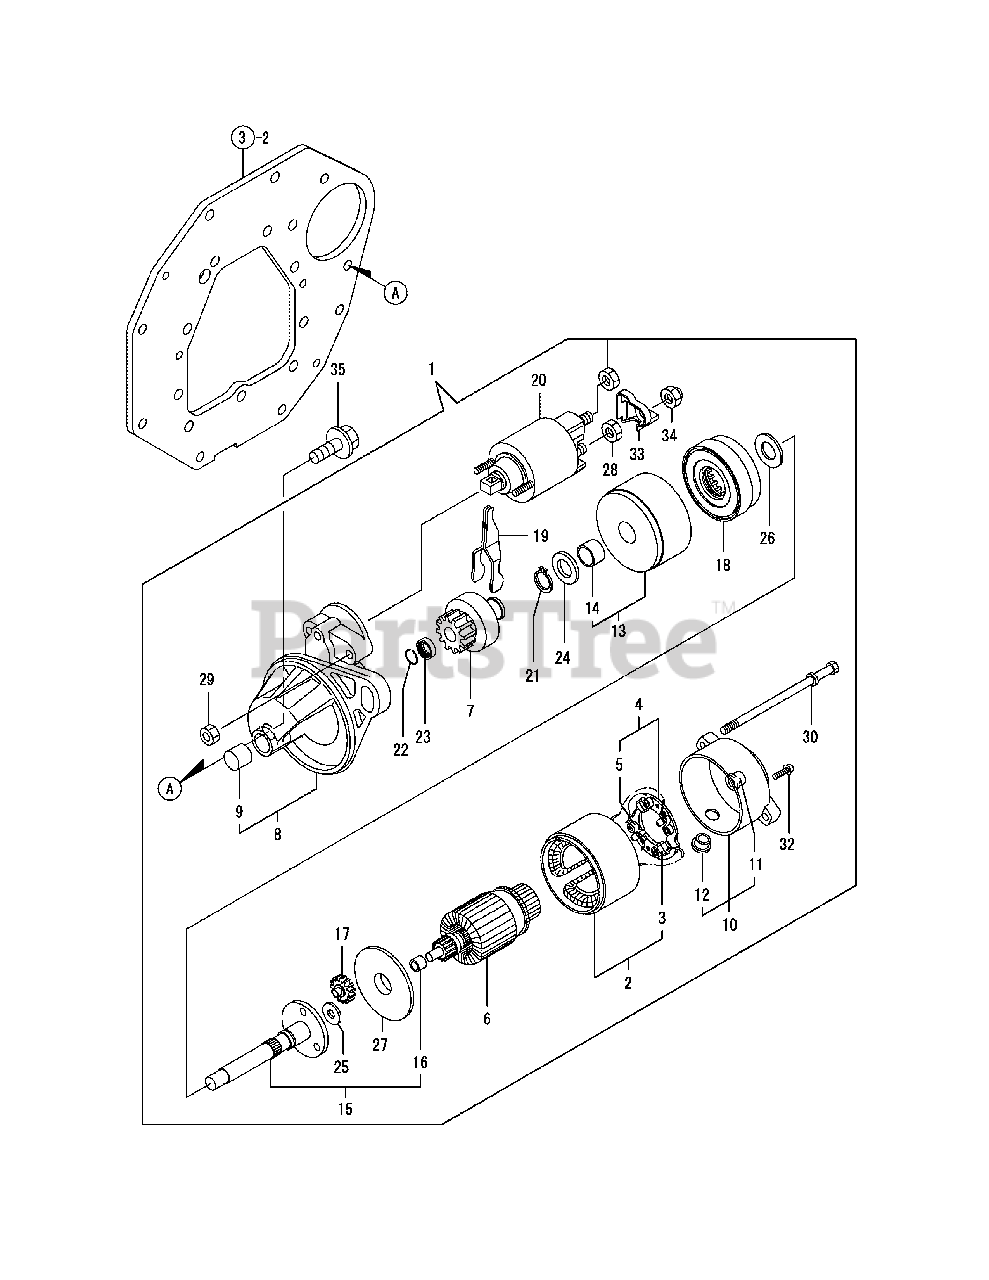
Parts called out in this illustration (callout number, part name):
2	Coil Assembly, Field
3	Starter Kit
4	Holder Assembly
5	Spring
6	Armature Assembly
7	Clutch Sub-Assembly
8	Housing Assembly, Starter
9	Needle Bearing
10	Frame Assembly
11	Bearing
12	Cover
13	Bearing Sub-Assembly
14	Bearing
15	Shaft Sub-Assembly
16	Bearing
17	Gear
18	Gear
19	Lever
20	Switch, Emergency
21	Ring
22	Ring
23	Nut
24	Washer
25	Washer
26	Washer
27	Plate
28	Nut
29	Nut
32	Screw, M 4 x 6
33	Cover Set, Terminal
34	Nut
35	Bolt, M 10 x 25 Plated
